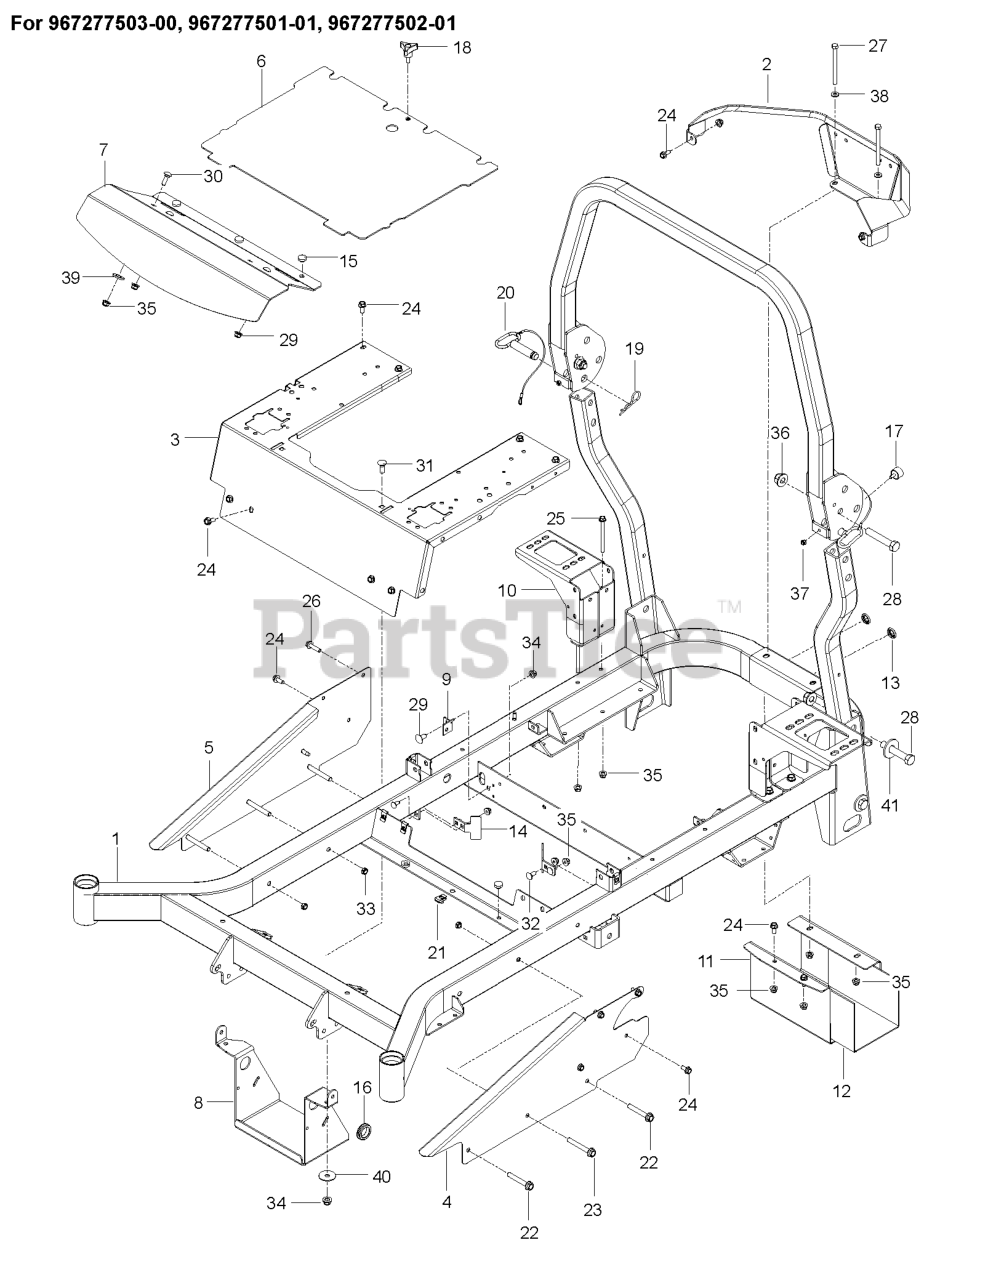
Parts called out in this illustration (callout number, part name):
1	KIT.FRAME.W/DECALS.X668
2	GUARD.PNT.REAR.MZ.GRAY
3	SUPPORT.PNT.SEAT.CONTROL.ORNG
4	SIDE.LT.ORANGE
5	SIDE.RT.ORANGE
6	PLATE, FLOOR W/DECALS
6	PLATE FLOOR ORANGE
7	PLATE FOOTREST ORANBE MS668
7	PLATE, FOOTREST
8	BRACKET.PNT.BATTERY.BLK
9	BRACKET.DAMPENER.BLACK
10	MOUNT, TANK, ZT BLK
11	SHIELD.MUFFLER.BLACK
12	HEAT SHIELD
13	CAP.PLUG.BP-1.BLACK
14	STOP, DECK, EZ+
15	GROMMET, BUMPER
16	RUBBER GROMMET
17	BUMPER, MALE STUD, 1/4-20
18	KNOB W/STUD
19	PIN HAIR .148 X 2-15/16 #210
21	U-CLIP 5/16-18 NUT RETAINER
22	HHFS 3/8-16 X 2.5 GR 5 ZD
23	HHFS 3/8-16 X 2-3/4 GR5 ZD
24	HHFS 5/16-18 X 3/4
25	BOLT.HEX.FLNG.5/16-18X3.75
26	HHFS 5/16-18 X 1.25 TPBLT GD 5
27	HCS 5/16C X 4
28	5/8-11 X 3-1/2 HHB GRADE 5
29	RP BOLT 5/16-18 X3/4 ZN/YEL GR
30	RHSNB 5/16C X 1
31	RHSNB 3/8C X 1
31	BOLT D
32	BOLT 5/16C X 3/4" CARRIAGE
33	NUT HEX 3/8-16 NYLON, THIN
34	NUT 3/8-16 HEX FLG NYLOC ZD
35	5/16-18 NYLOC FLANGE NUT
36	NUT 5/8-11 FLG NYLOC ZD
37	NUT.1/4-20.HEX.NYLOC.ZD
38	WASHER
39	WASHER 1/2" FLAT
40	WASHER.13/32X1-1/2X16GA
41	WASHER, 5/8 FLAT
